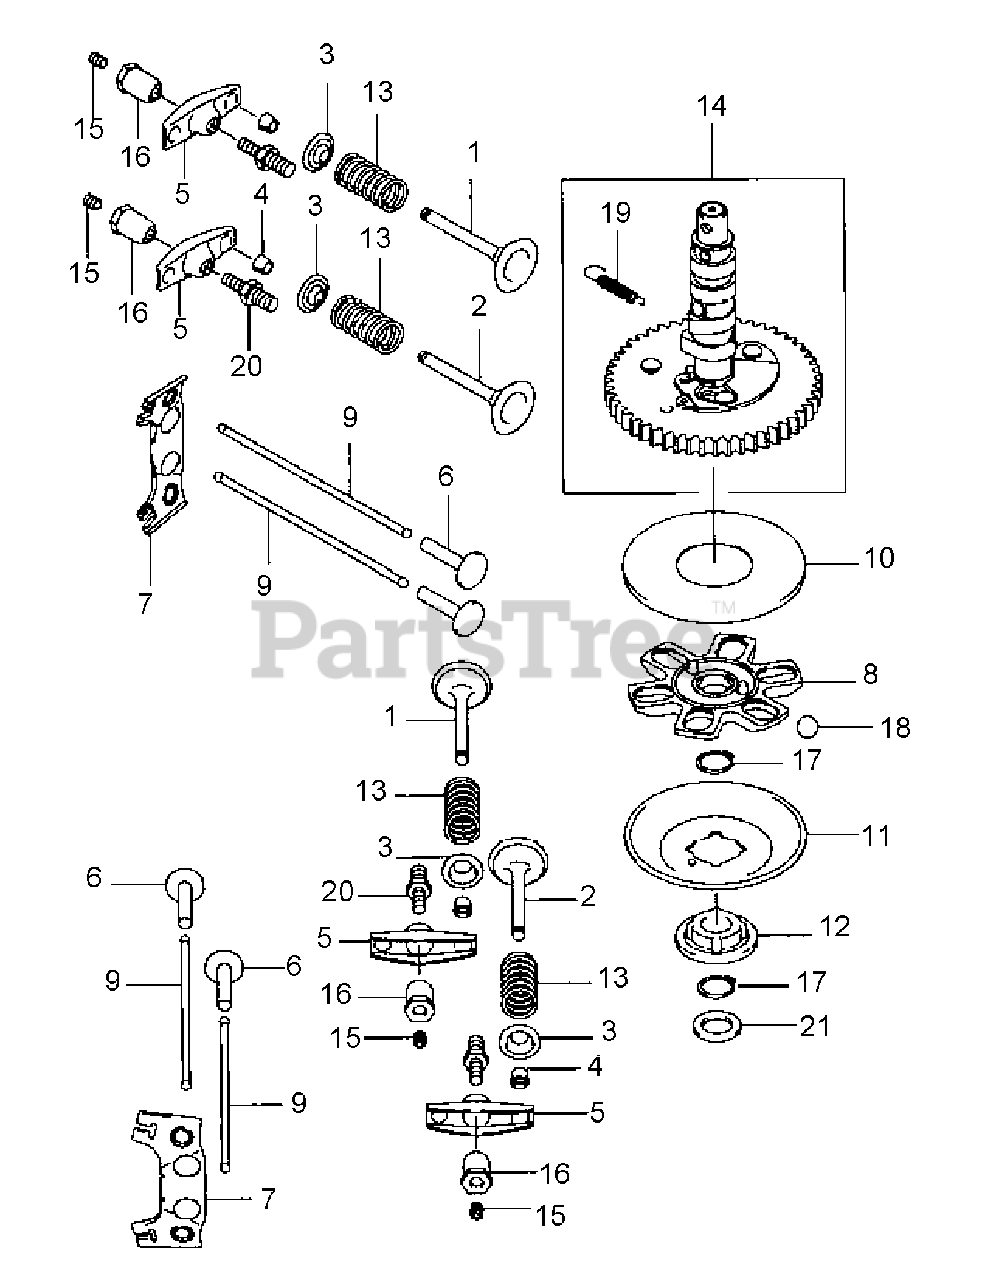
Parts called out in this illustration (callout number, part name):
1	VALVE-INTAKE
2	VALVE-EXHAUST
3	RETAINER-VALVE SPRING
11	PLATE, GOVERNOR
13	SPRING-ENGINE VALVE
14	CAMSHAFT-COMP
17	RING-SNAP
18	BALL
19	SPRING
